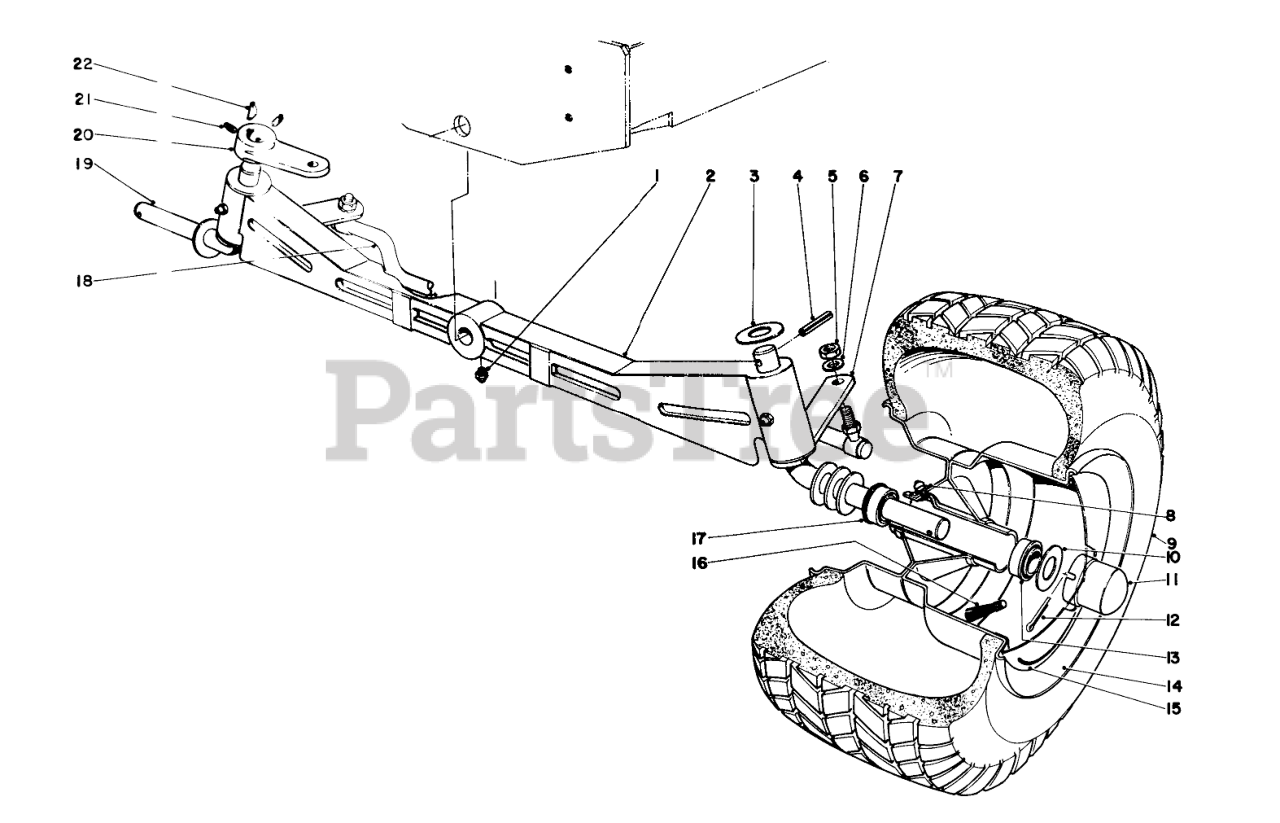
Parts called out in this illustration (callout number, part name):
1	Zerk Fitting
2	Front Axle Housing
3	WASHER-FLAT
4	PIN-ROLL
5	NUT-HEX
6	WASHER-LOCK
7	Axle Assy., L.H.
8	FITTING-GREASE
9	Tire
10	WASHER-FLAT
11	Hub Cap
12	PIN-COTTER
13	Bearing, Outer
15	Hub Cap 960
16	VALVE -STEM
17	Bearing, Inner
18	Tie Rod
19	Axle Assy., R.H.
20	Steering Lever
21	SCREW-SQH
22	KEY-WOODRUFF
